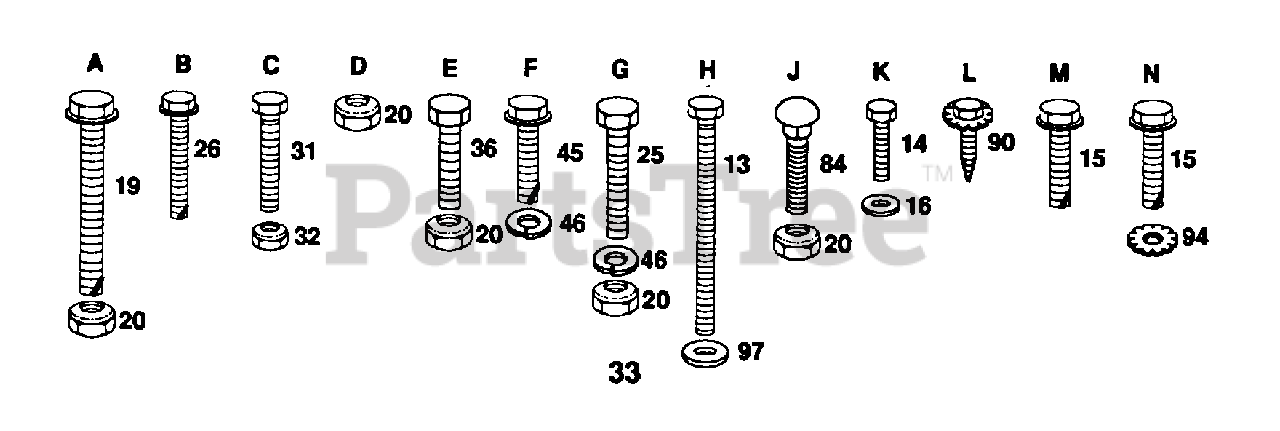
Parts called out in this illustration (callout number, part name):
13	"BOLT,HEX"
14	BOLT
15	SCREW
16	LOCKWASHER
19	BOLT
25	BOLT
26	SCREW
31	BOLT
33	STRAP LOCATOR
45	SCREW
46	WASHER
84	BOLT
94	LOCKWASHER
97	WASHER T
